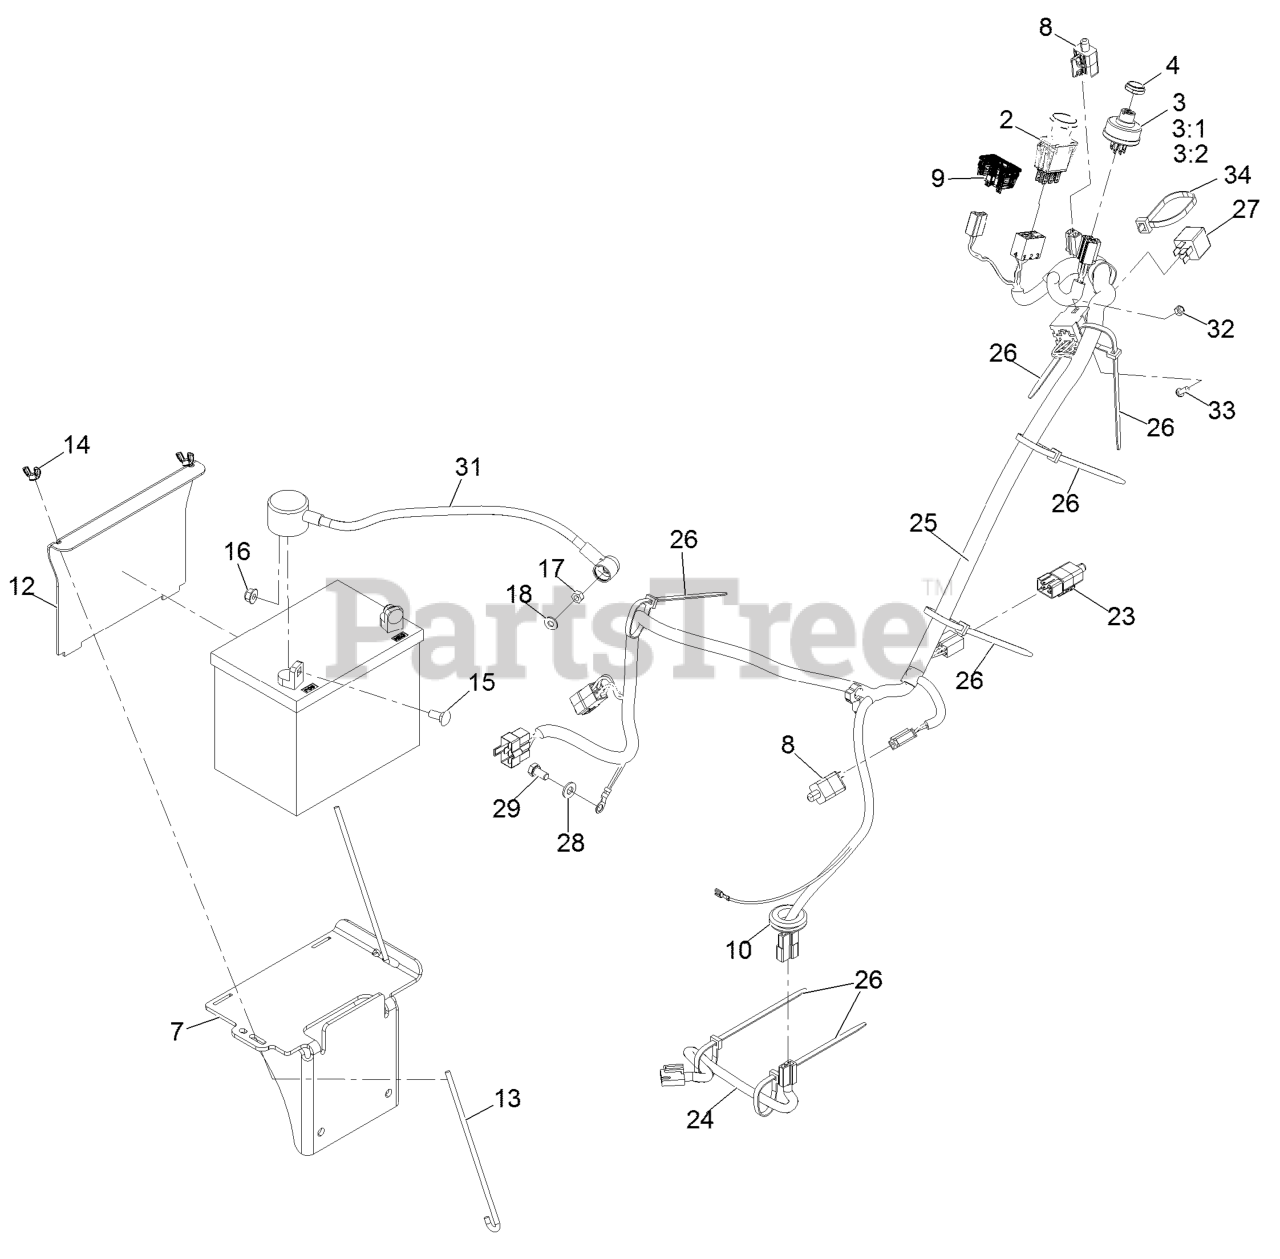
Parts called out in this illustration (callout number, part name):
2	SWITCH-PTO
3:1	WASHER-LOCK
4	NUT-SWITCH, IGNITION
7	WELD, BATTERY MOUNT
9	METER-HOUR
10	GROMMET
12	BRACKET, BATTERY HOLD DOW
13	BOLT-HOLDDOWN
14	WINGNUT
15	BOLT-CARR
16	NUT-HF, NI
17	NUT-HEX
18	WASHER-FLAT
23	SWITCH, 2 POLE
24	HARNESS-CLUTCH PIGTAIL
25	HARNESS-MAIN
26	TIE-PLASTIC
28	WASHER-PLAIN
29	SCREW-HH
31	ASM,POSITIVE BATTERY CABL
32	NUT-LOCK, NI
34	TIE-PLASTIC
